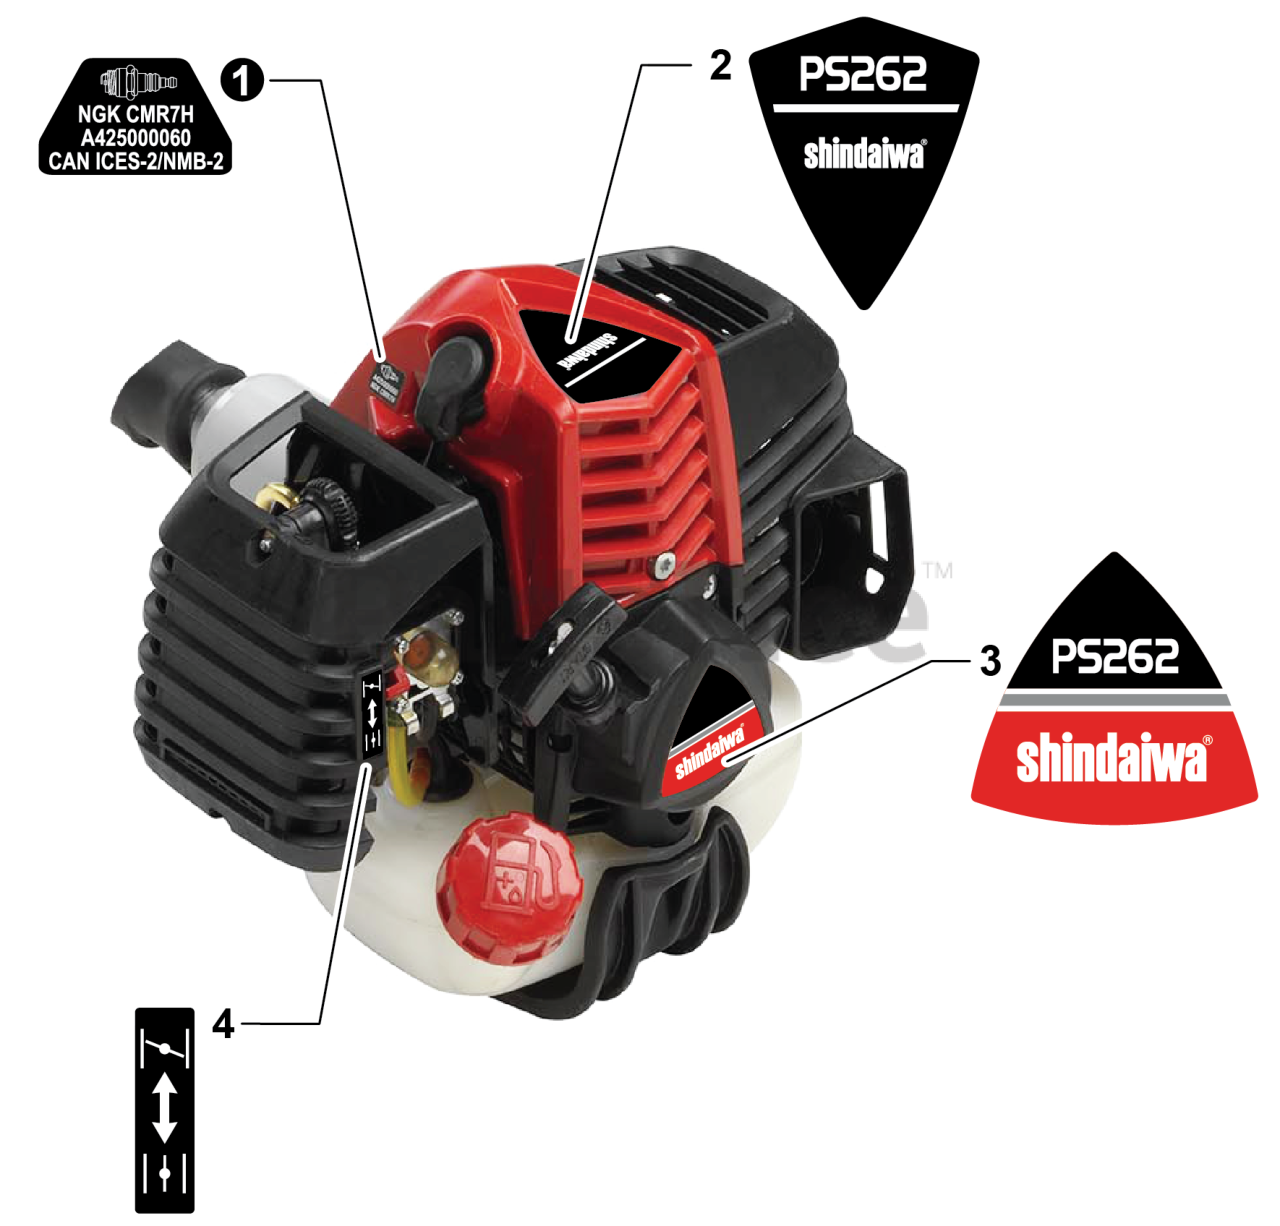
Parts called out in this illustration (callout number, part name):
1	LABEL - SPARK PLUG - CMR7H
2	LABEL - MODEL PS262
3	LABEL - STARTER - PS262
4	LABEL - CHOKE
